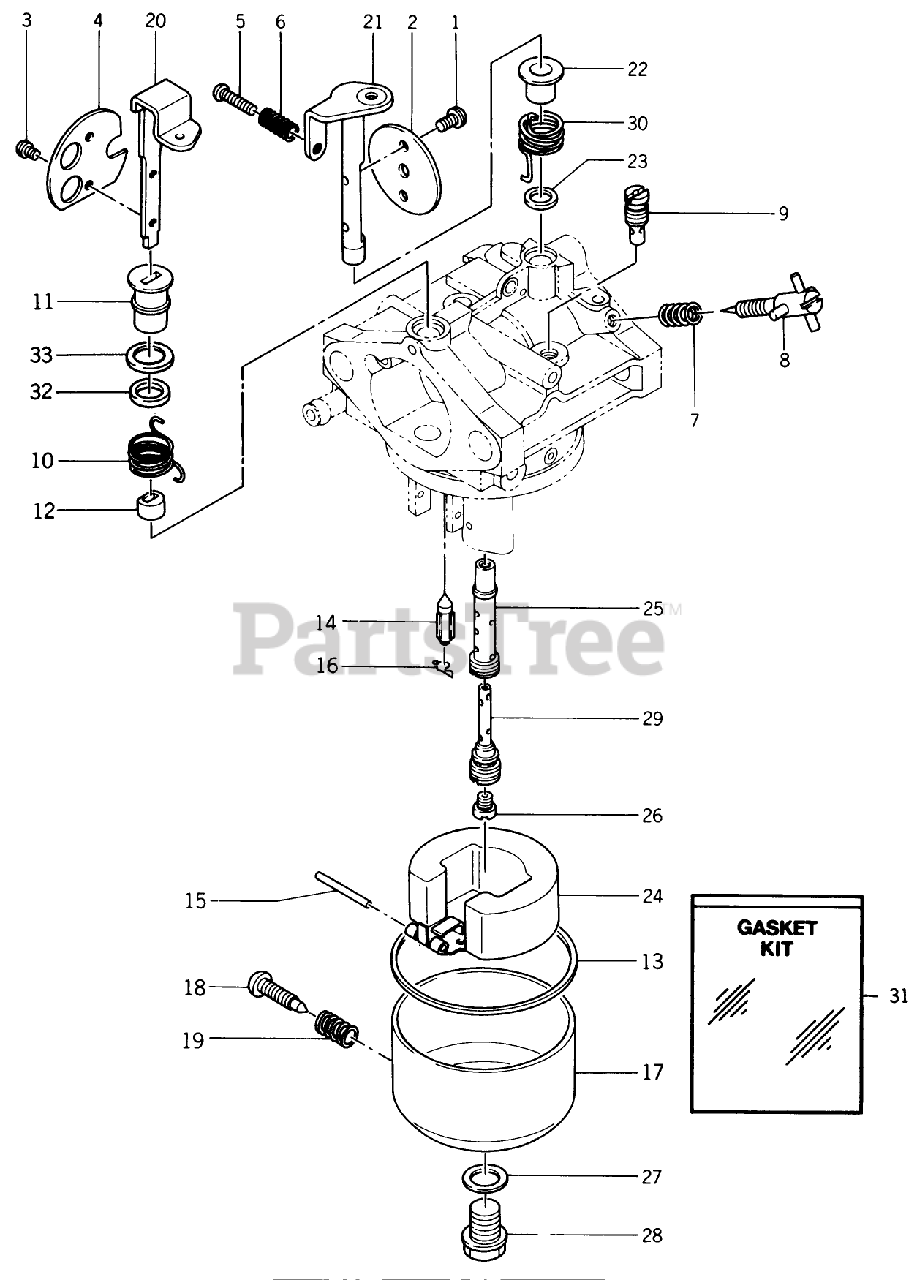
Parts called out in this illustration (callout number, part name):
2	Throttle Valve (#120)
4	Choke Valve
9	Pilot Jet (#62.5)
14	Needle Valve Assy
17	Float Chamber Assy (includes items 18 19).
20	Shaft-Choke
21	Shaft-Throttle
25	Main Nozzle (#13B)
26	Main Jet (#117.5)
29	Main Jet Holder
31	Carburetor Gasket Set
